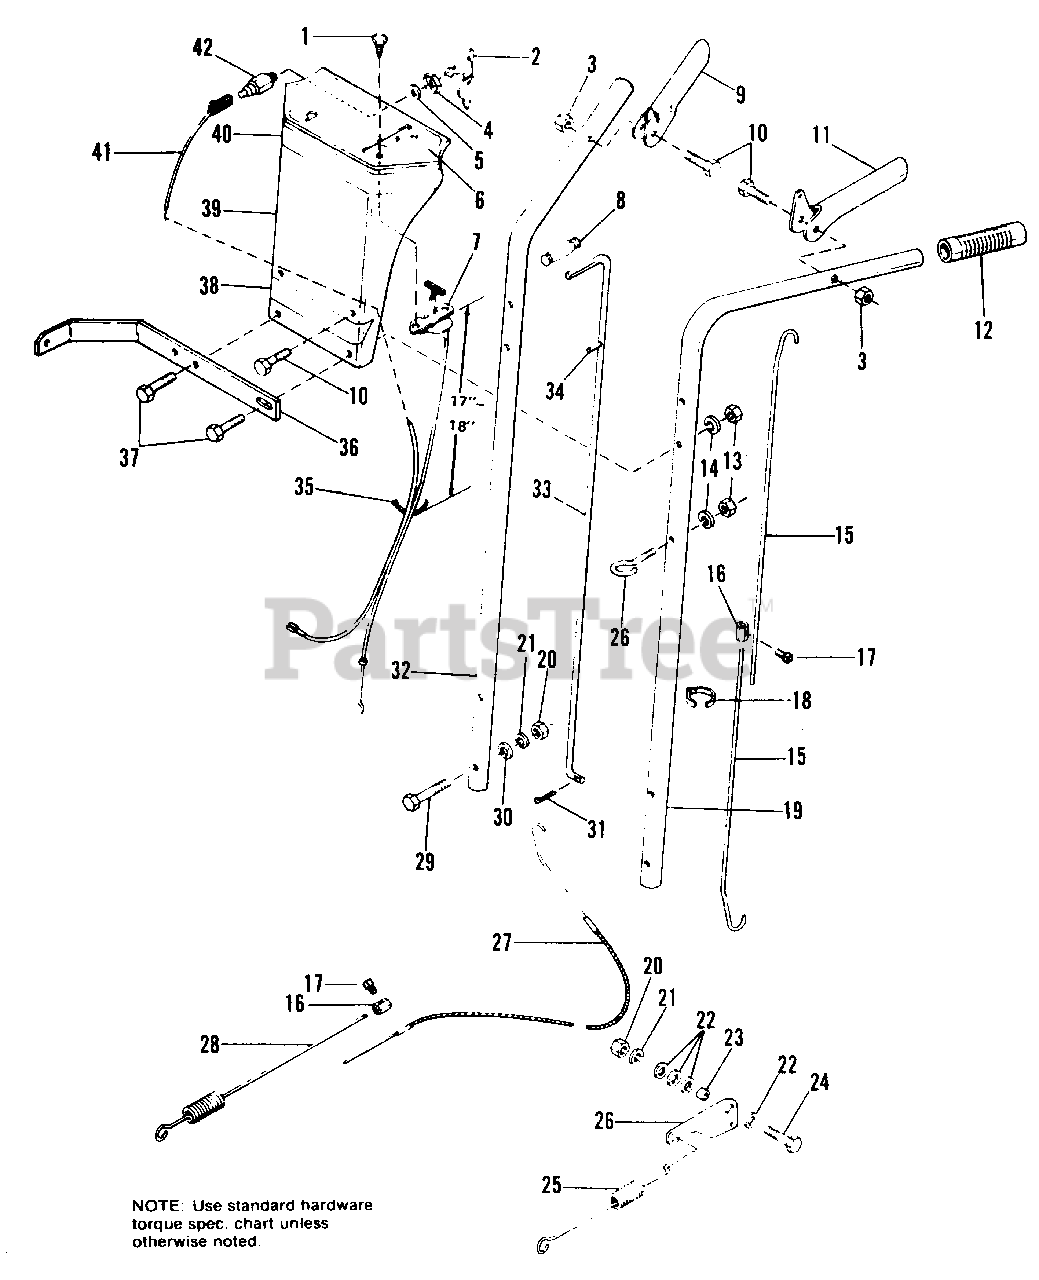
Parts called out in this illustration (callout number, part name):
1	SCREW, Thd Forming, 1/2-20 x 1/2
2	KEY & RING ASSY.
3	LOCKNUT, Hex, 1/4-20
4	NUT, Hex, 5/8
5	LOCKWASHER, Int. Tooth, 5/8
6	DECAL, Instructions
7	CONTROL ASSY. (1690305 Only)
7	CONTROL ASSY. (1690378 Only)
9	GRIP, Clutch, R.H.
10	CAPSCREW, Hex, 1/4-20 x 1-3/4
11	GRIP, Clutch, L.H.
13	NUT, Hex, 1/4-20
14	LOCKWASHER, Spring, 1/4
15	WlRE, Control
16	CLAMP, Wire
17	SETSCREW, Sq. Hd, #10-24 x 5/8
18	CLIP, Spring
19	HANDLE, L.H.
20	NUT, Hex, 3/8-16
21	LOCKWASHER, Spring, 3/8
22	WASHER, Plain, 5/16
24	CAPSCREW, Hex Hd. 3/8-16 x 1-1/4
26	ARM, Pivot
27	ABLE & WIRE ASSY. (1690305 Only)
27	WIRE CONTROL, Upper (1690378 Only)
29	CAPSCREW, Hex Hd., 3/8-16 x 2
30	WASHER, Plain, 3/8
31	PIN, Cotter, 3/32 x 3/4
32	HANDLE, R.H.
33	ROD ASSY.
36	BRACKET, Support
37	CAPSCREW, Hex Hd., 1/4-20 x 1-1/2
38	DECAL, Simplicity
39	HOUSING ASSY.
40	DECAL, Strip
41	WIRE ASSY.
42	SWITCH (1690305 Only)
42	SWITCH (1690378 Only)
